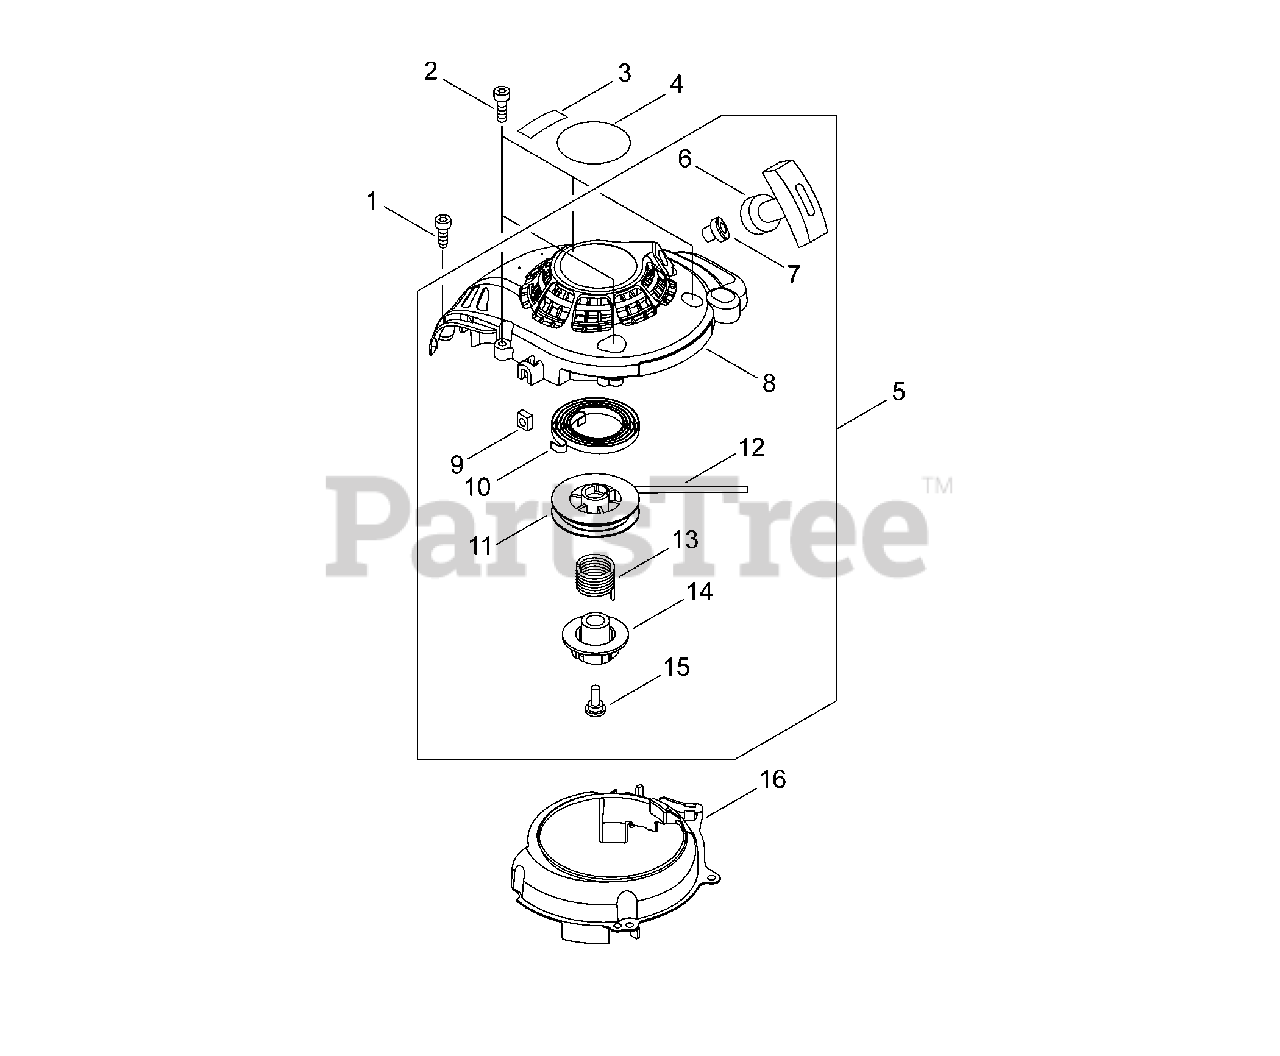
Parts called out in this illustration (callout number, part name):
1	BOLT, TORX 4×16
2	BOLT, TORX 4×16
3	LABEL, MODEL
4	LABEL, RECOIL STARTER
5	STARTER ASSY, RECOIL
6	GRIP, STARTER
7	GUIDE, ROPE
8	CASE, STARTER
9	NUT M5
10	SPRING, RECOIL
11	REEL, ROPE
12	ROPE, STARTER 3×700
13	SPRING, TORSION
14	PLATE, CAM
15	SCREW
16	COVER, FAN
